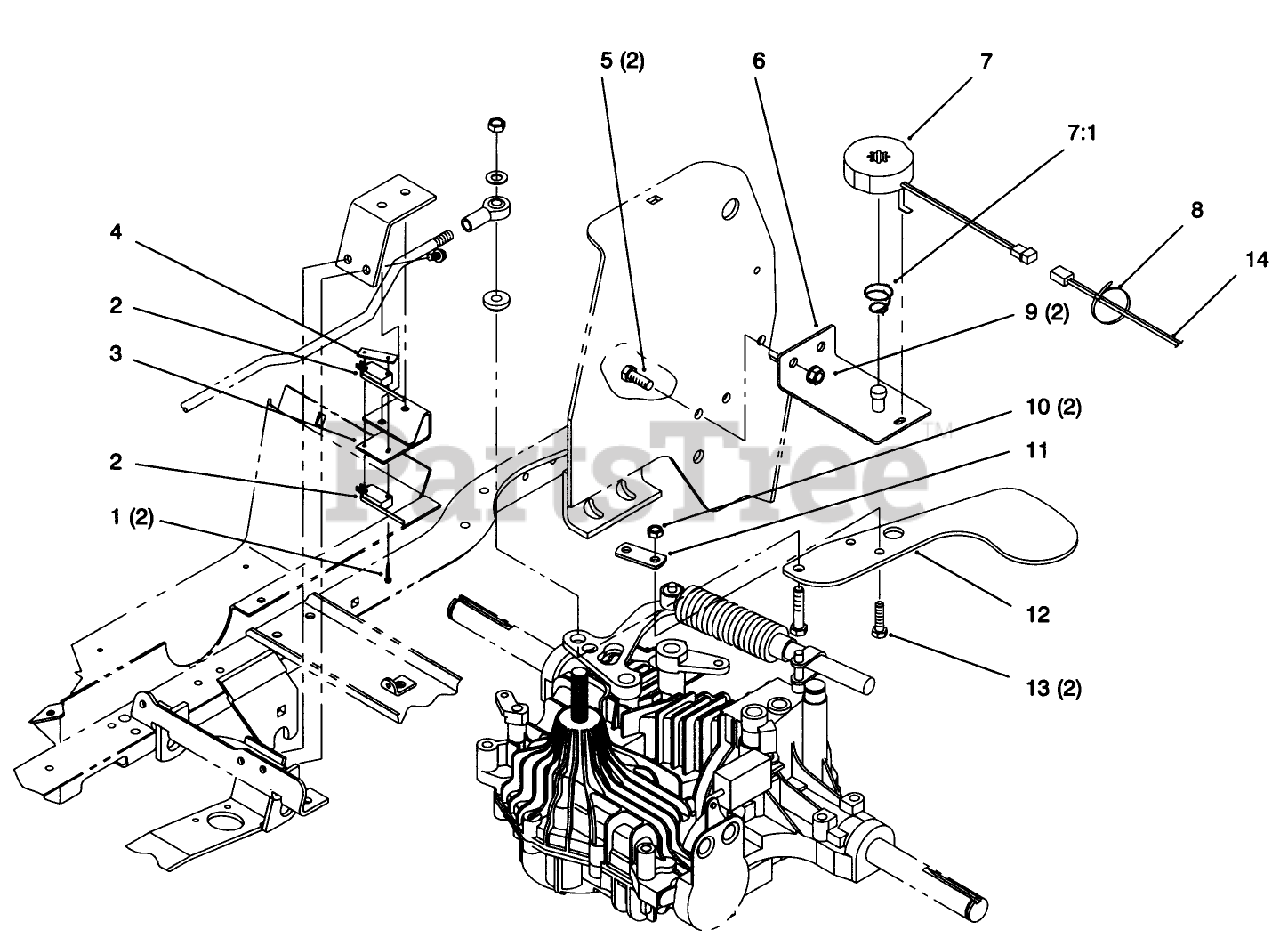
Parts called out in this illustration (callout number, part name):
1	SCREW-HH
2	SWITCH-MICRO
3	BRACKET-BRAKE SWITCH
4	NUT-SPEED
5	SCREW-HH
7:1	SPRING-COMPRESSION
8	TIE-CABLE
9	NUT-LOCK, NI
10	NUT-LOCK, NI
11	CLAMP - CRUISE
12	ARM - CRUISE
13	SCREW-HH
